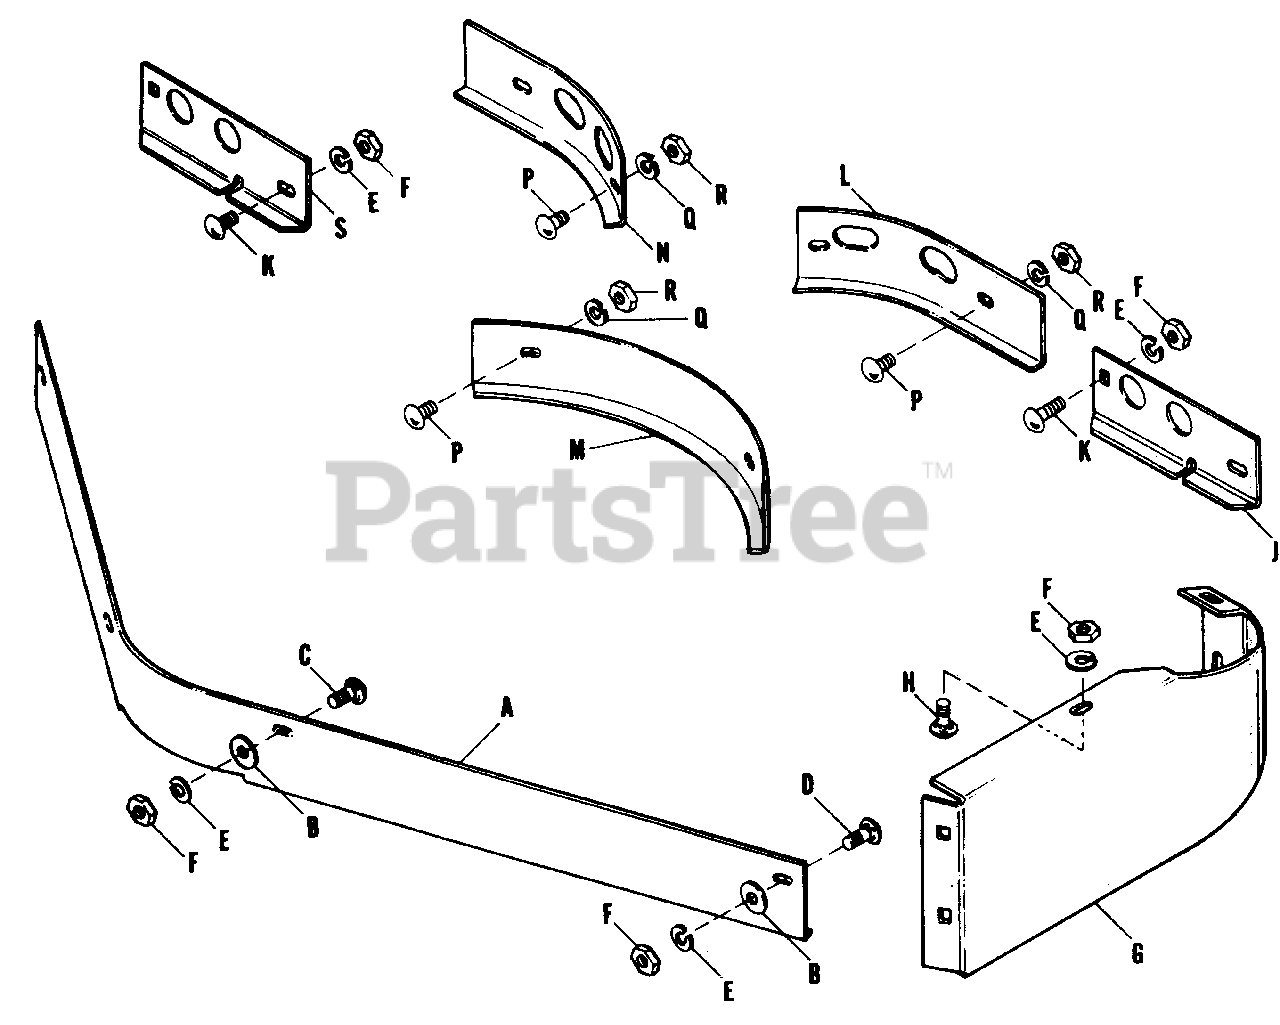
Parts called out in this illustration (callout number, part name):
A	Front Mulcher Baffle
B	Washer, Plain, 3/8" Std.
C	Carriage Bolt, 3/8"-16 x 3/4" lg., w/sq. neck
D	Carriage Bolt, 3/8"-16 x 3/4 lg.
E	Washer, Lock, 3/8"
F	Nut, Hex, Full, 3/8-16
G	Housing End Plate
H	Carriage Bolt, 3/8"-16 x 3/4" lg.
J	L.H. Rear Baffle
K	Carriage Bolt, 3/8"-16 x 1" lg.
L	L.H. Rear Mulcher Baffle
M	Center Rear Mulcher Baffle
N	R.H. Rear Mulcher Baffle
P	Carriage Bolt, 5/16"-18 x 3/4" lg., w/sq. neck
Q	Washer, Lock, 5/16"
R	Nut, Hex, Full, 5/16"-18
S	R.H. Rear Baffle
